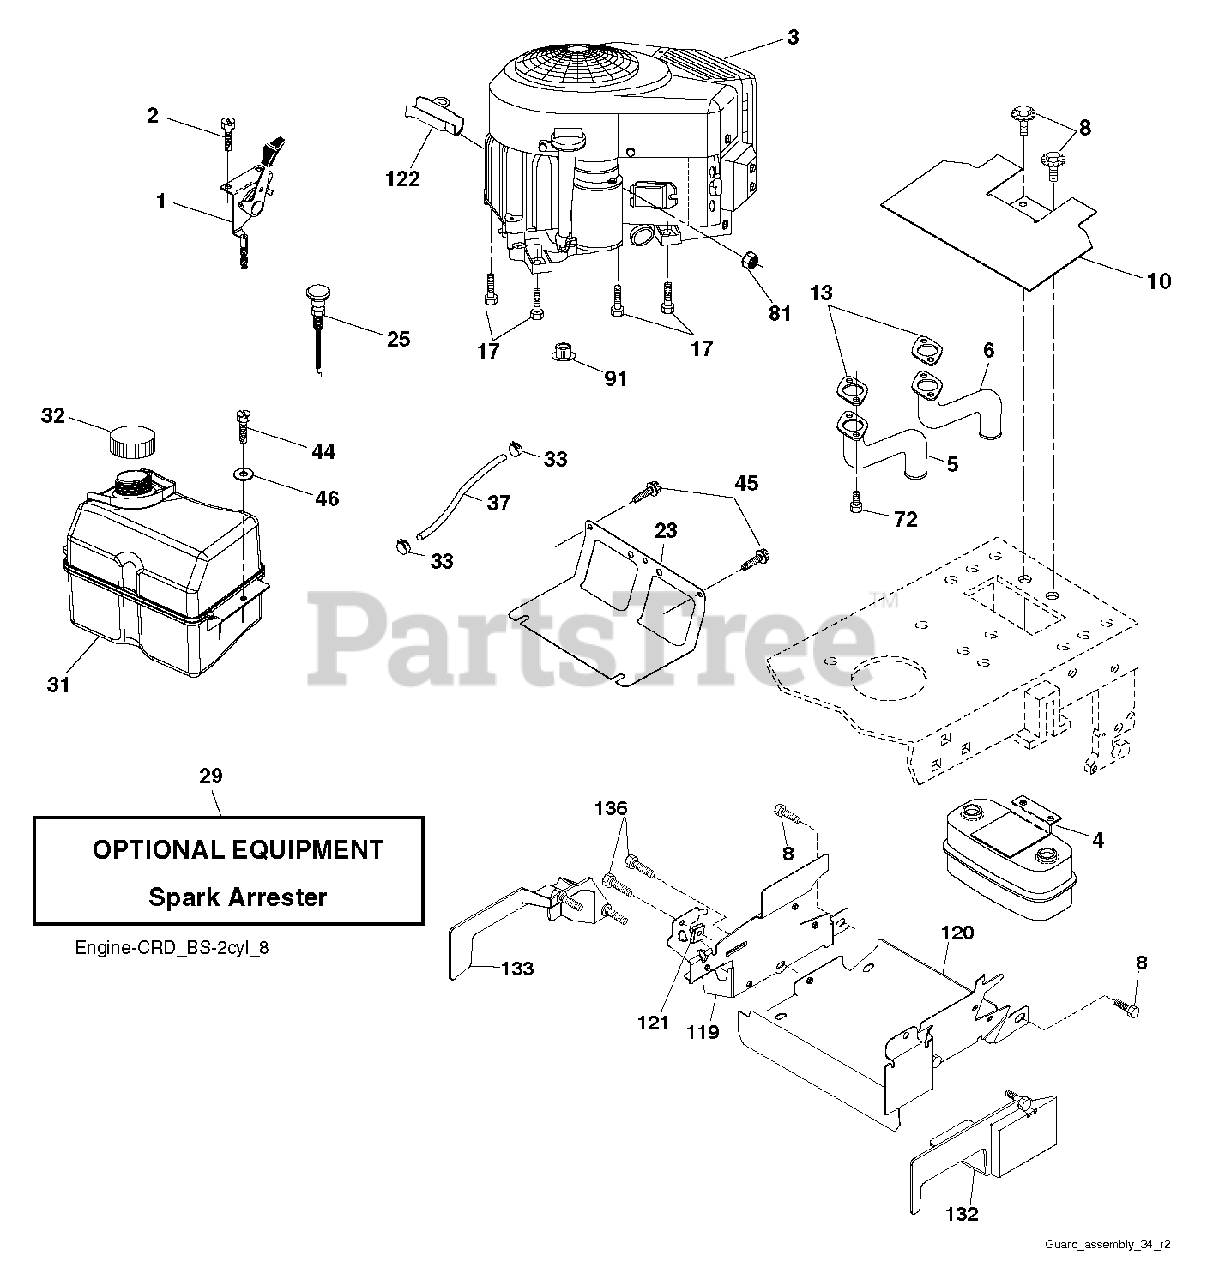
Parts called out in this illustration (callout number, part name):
1	THROTTLE CABLE
2	SCREW.#10 X 0.750.BOS THREAD
4	MUFFLER.TWIN.CYL.LOW.TONE
5	EXHAUST TUBE RH
6	TUBE MANIFOLD LH
8	BOLT, 5/16-18 X 1 3/4
10	RP SHIELD HEAT MUFFLER
13	GASKET.MUFFLER
17	SCREW.3/8-16
23	SHEILD.BROWNING.DBR.GUARD
25	CONTROL CHOKE
29	ARRESTER SPARK (OPTIONAL)
32	CAP ASM.FUEL.2.25"FR.
33	HOSE CLAMP
37	LINE.FUEL.20
44	SCREW HEXWSHR 1/4-20X3/4
45	SCREW, 3/8-16X3/4
46	WASHER
72	SCREW.SOCKET.HEAD.5/16-18
81	NUT
91	BUSHING.1.375OD
122	EXTENSION DRAIN OIL
136	SCREW.1/4-20X5/8
